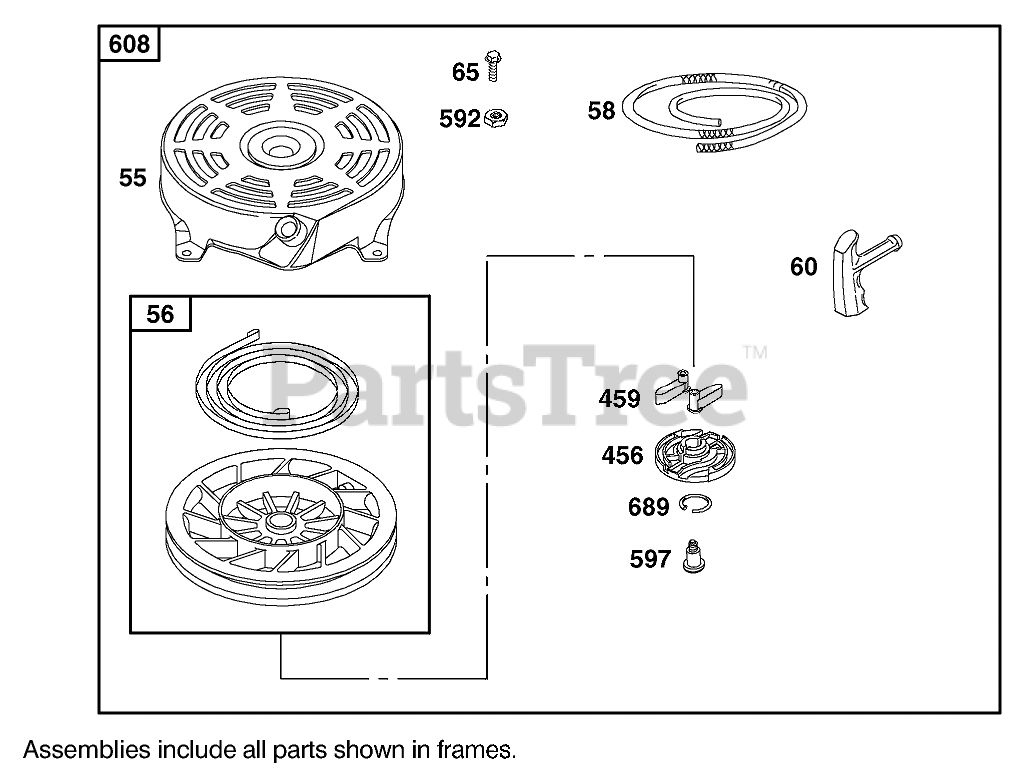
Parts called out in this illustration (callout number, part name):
56	PULLEY-STARTER, REWIND
58	ROPE-STARTER
65	SCREW-HH
456	RETAINER-STARTER, REWIND
459	PAWL-STARTER
592	NUT-HEX
608	REWIND ASM
689	SPRING-TORSION
